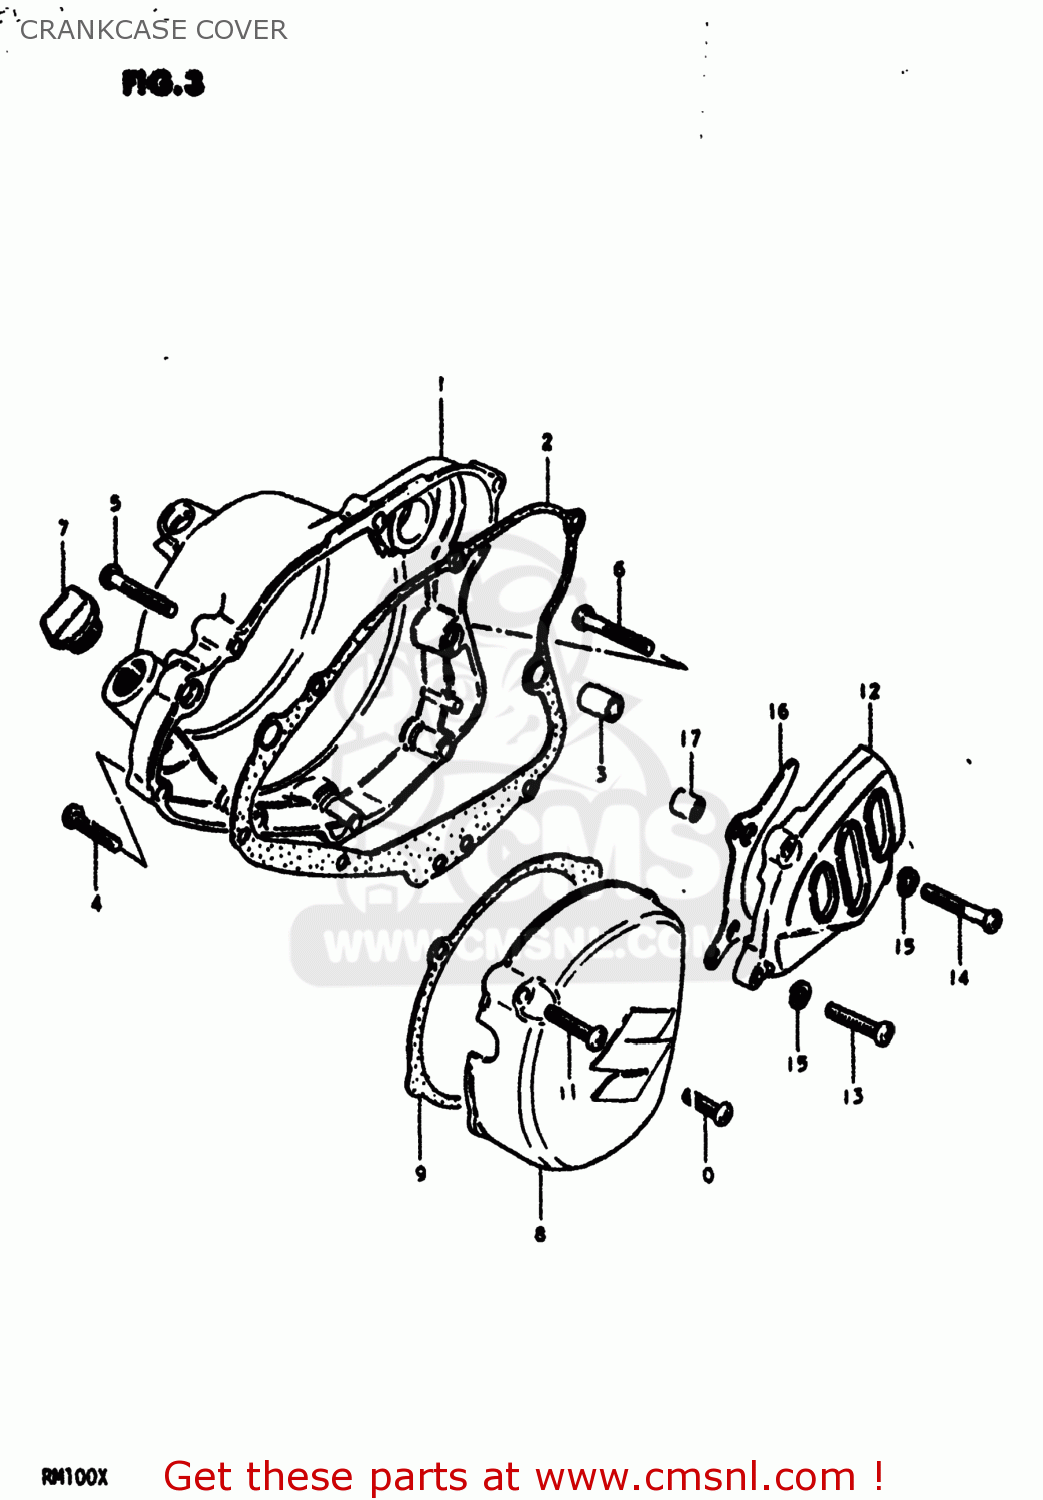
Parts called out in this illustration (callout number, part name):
1	COVER,CLUTCH
2	GASKET,CLUTCH COVER (MCA)
3	PIN
4	SCREW 6X30
5	SCREW
6	SCREW (6X45)
7	PLUG,OIL FILTER
8	COVER
9	GASKET,MAGNETO COVER (MCA)
10	SCREW
11	SCREW,6X30
12	COVER,ENGINE SPROCKET
13	BOLT 6X35
14	SCREW (6X45)
15	LOCK WASHER
16	PLATE,CHAIN FRONT GUIDE
17	SPACER(6.5X10.5X12)
